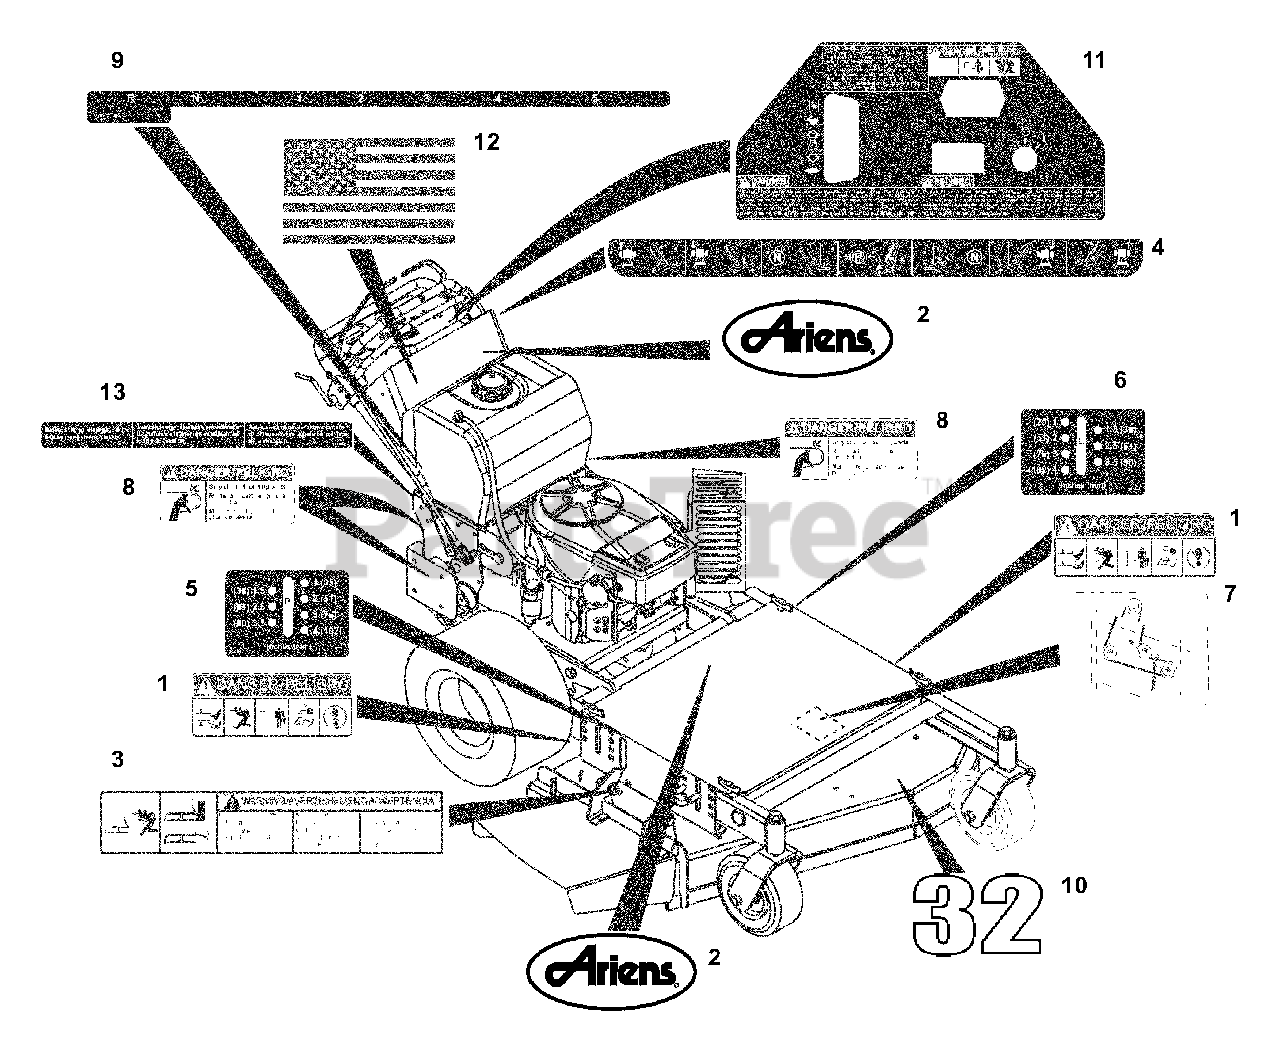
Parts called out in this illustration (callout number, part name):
1	DECAL, MOWER PAN DANGER
2	DECAL, ARIENS
3	DECAL, WARNING
4	DECAL-STEER LEVERS-GEAR-ERGO
5	DECAL-HEIGHT OF CUT-FIXED - RH
6	DECAL-HEIGHT OF CUT-FIXED - LH
7	DECAL-BELT DIAGRAM-2 SPINDLE
8	DECAL-DANGER-BELT ROTATING
9	DECAL-SHIFT LEVER
10	DECAL, 32
11	DECAL-CONTROL GR13-ERGO
12	DECAL, AMERICAN FLAG
13	DECAL - DECLUTCH - GEAR
